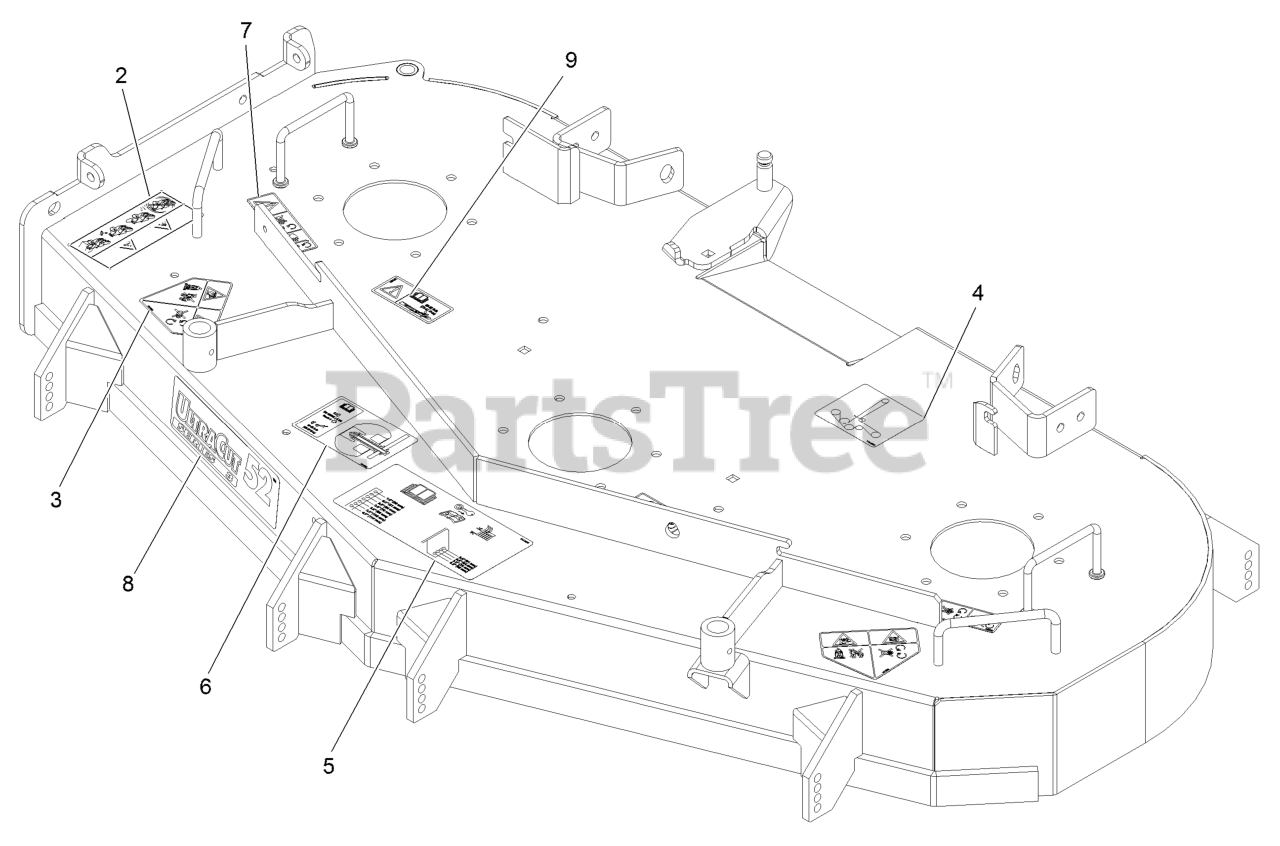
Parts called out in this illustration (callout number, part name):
2	DECAL-WARNING, BAGGER
3	DECAL-DANGER
4	DECAL-BELT ROUTING
5	DECAL-ANTI-SCALP
6	DECAL-ROLLER MOUNTING
7	DECAL-COVER, MISSING
8	DECAL-ULTRACUT 52 SERIES
9	DECAL-BOLT TORQUE
